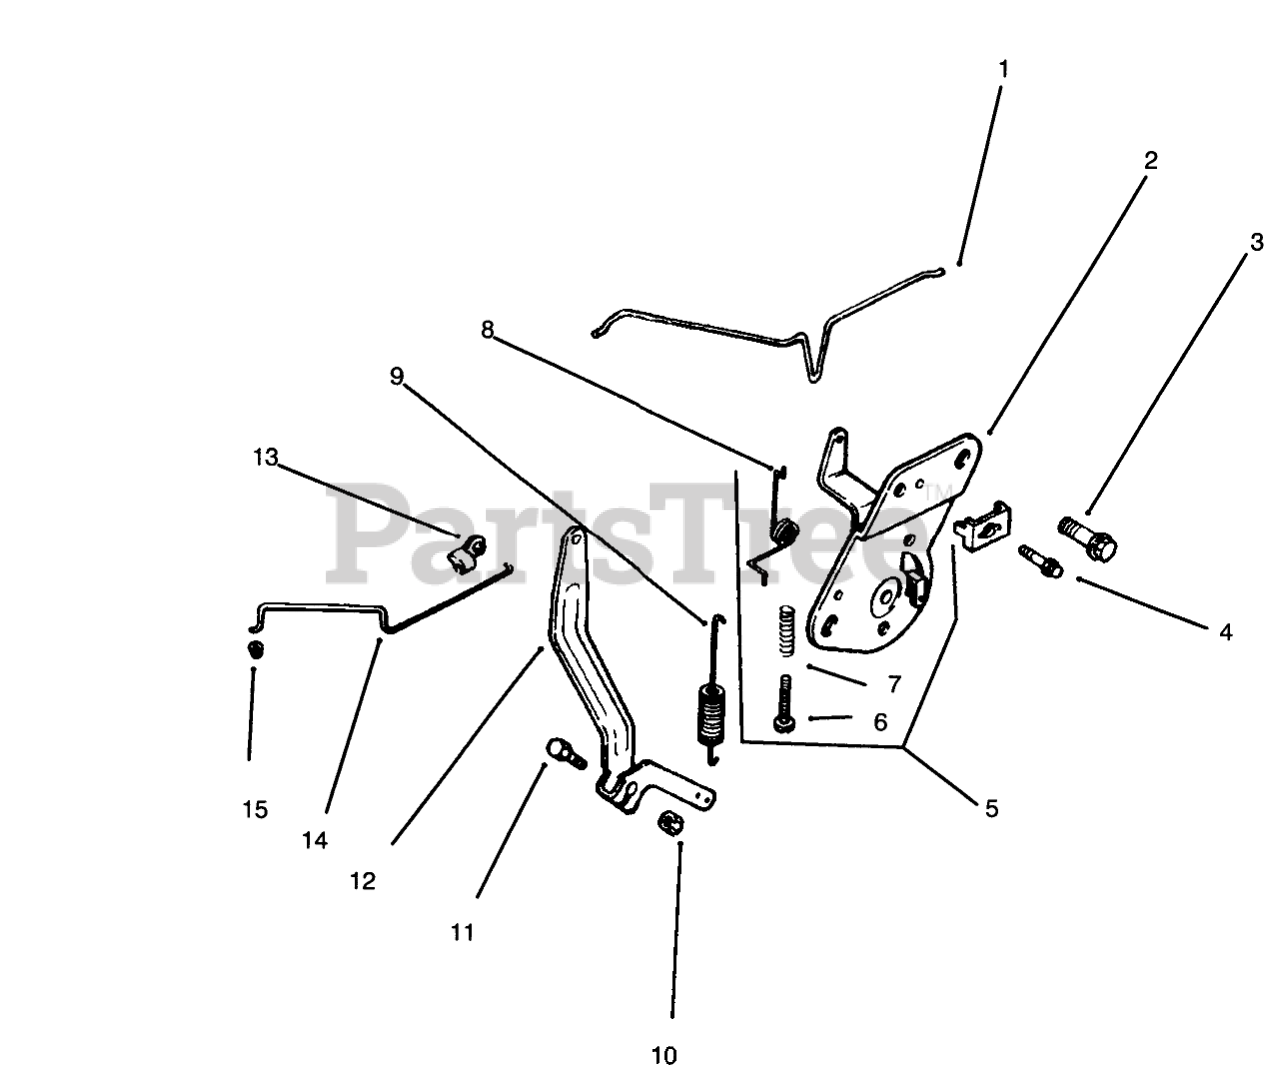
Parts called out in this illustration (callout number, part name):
1	Linkage-Choke
3	Screw
4	Screw
5	Control-Speed (Incl. Ref. #6-8)
7	Spring
8	Spring-Choke
9	Spring-Governor
11	Screw
12	Lever
13	Bushing
14	Linkage-Throttle
15	Bushing
